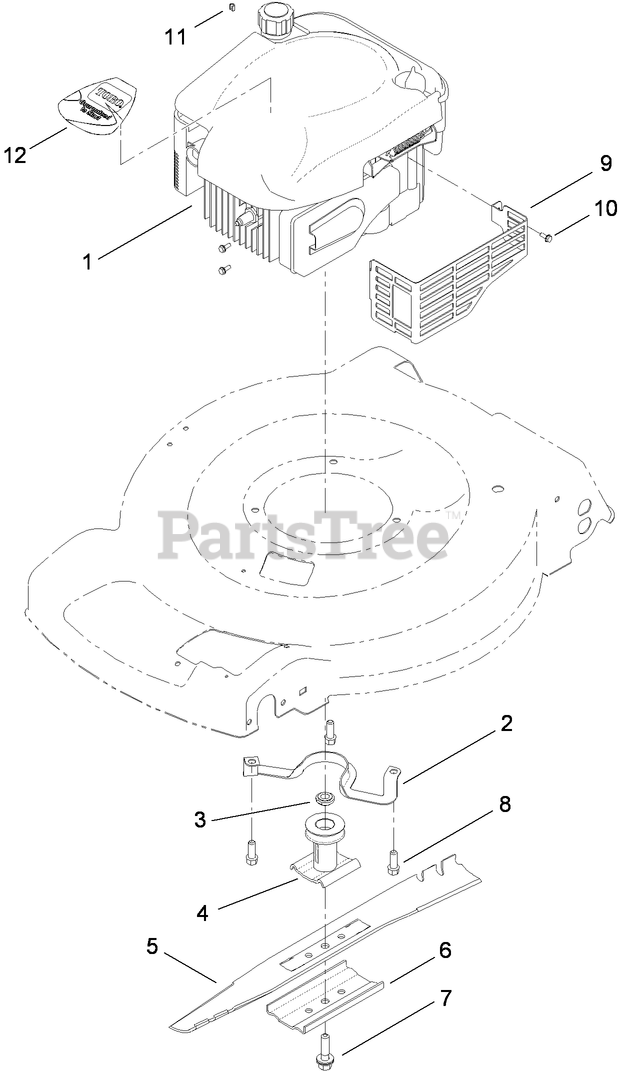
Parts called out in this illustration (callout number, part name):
2	GUIDE-BELT
3	SPACER-DRIVER
4	DRIVER-BLADE
6	SUPPORT-BLADE
8	SCREW-TAPTITE
9	SHIELD-MUFFLER
10	SCREW-TAPTITE
11	STOP-ROPE
